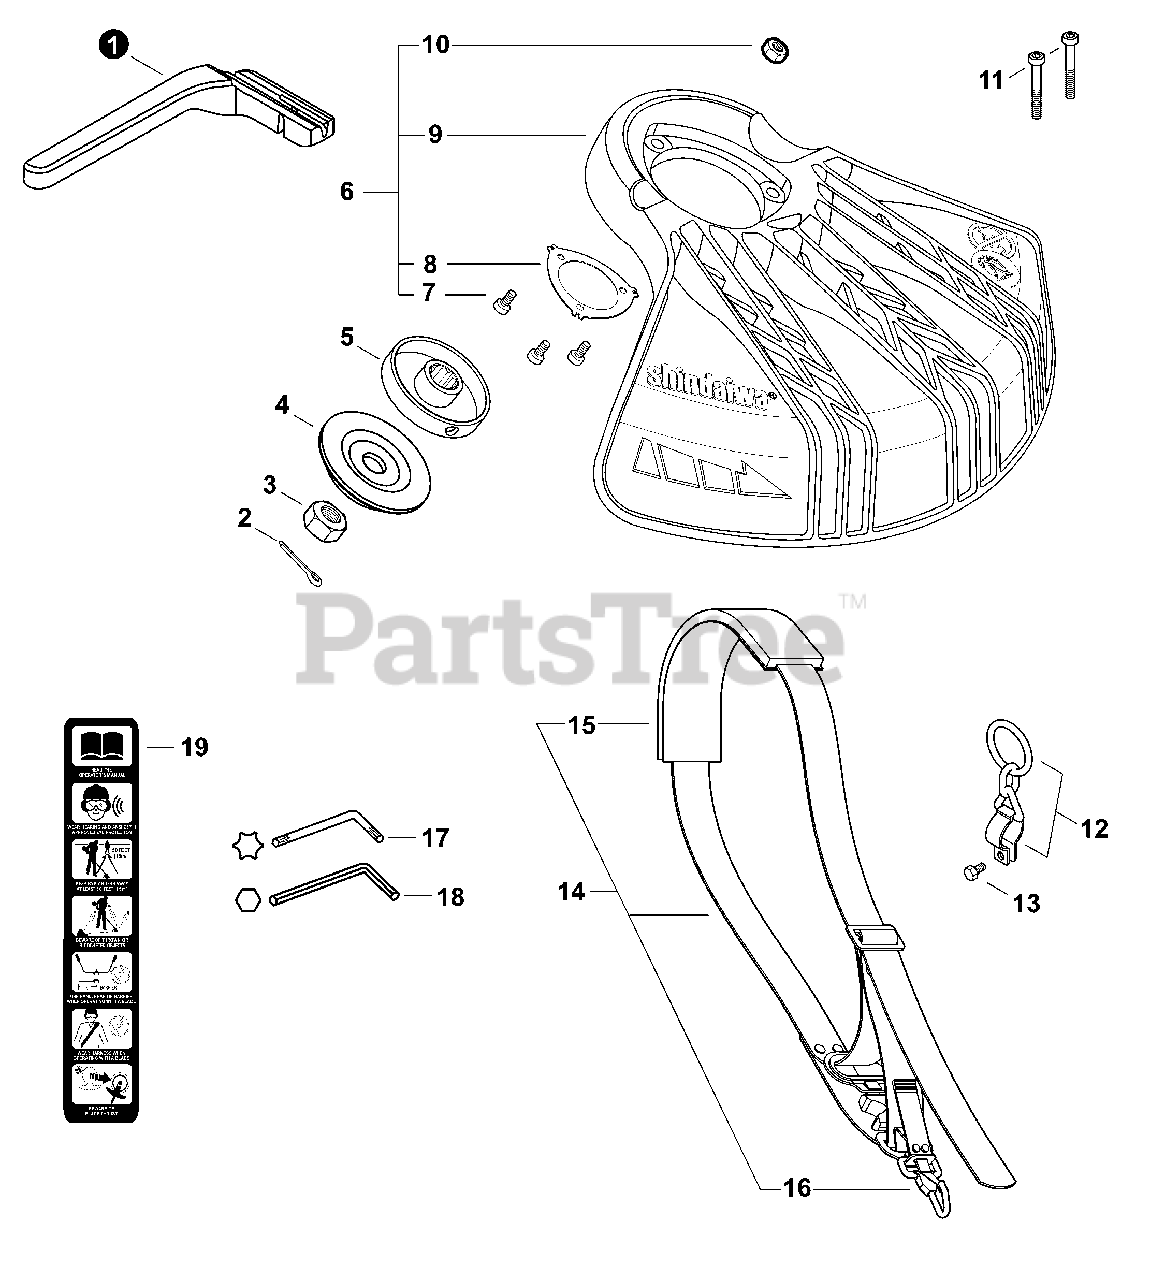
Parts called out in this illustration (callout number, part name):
1	BAR, BARRIER
2	PIN, COTTER 2×22
3	NUT 10×1.25 lH
4	PLATE, LOWER ADAPTOR
5	PLATE, UPPER ADAPTOR
6	SHIELD ASY
7	BOLT, TORX 5
8	PLATE, SHIELD
9	SHIELD, PLASTIC DEBRIS Ø49.5 mm
10	LOCK NUT 5
11	BOLT 5×35
12	HANGER ASSY, HARNESS
13	BOLT 5×12
14	HARNESS ASSY, SHOULDER
15	PAD, SHOULDER
16	HOOK,E24 SNAP
17	WRENCH, TORX T27 80×30
18	WRENCH, ALLEN 4mm
19	LABEL, CAUTION (BLADE CAPABLE)
